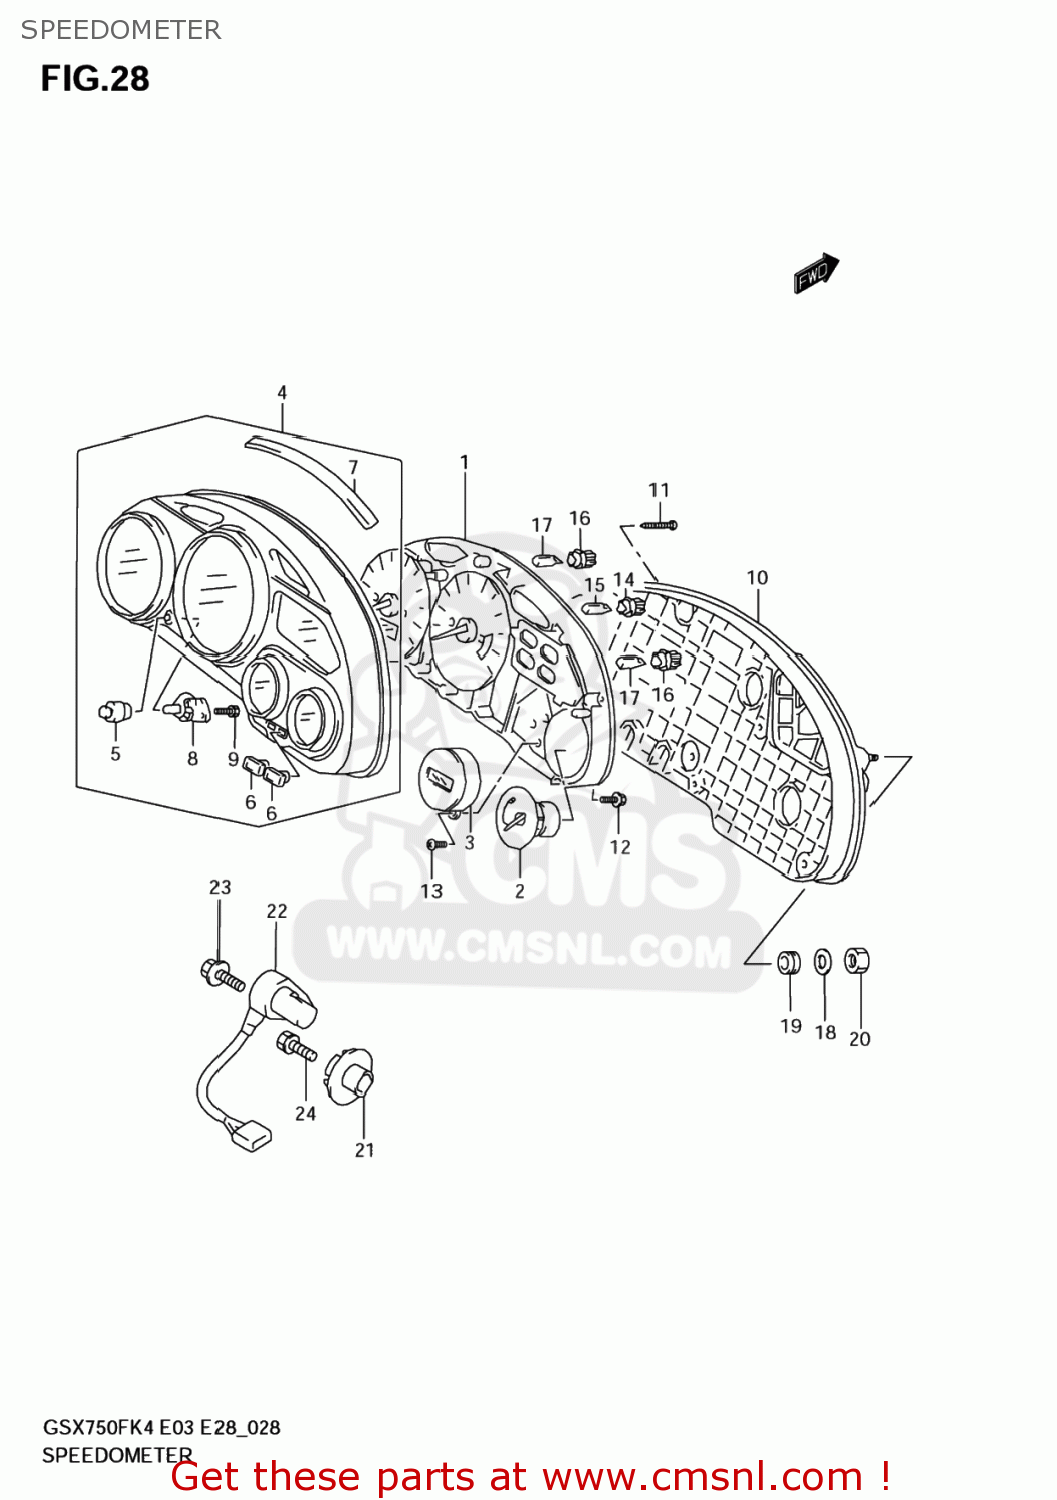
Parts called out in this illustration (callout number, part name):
1	SPEEDOMETER
2	FUEL,METER
3	CLOCK ASSY
4	VISOR ASSY
5	SWITCH,GUM
6	SWITCH,GUM
7	PACKING (NAS)
8	ATTACHMENT,SWITCH
9	SCREW(3X10)
10	CASE ASSY
11	SCREW
12	SCREW
13	SCREW
14	SOCKET(T:6.5)
15	BULB(12V1.7W,T6.5)
16	SOCKET
17	BULB(14V1.4W,T5)
18	WASHER(6.5X22X1.6)
19	CUSHION
20	NUT 6MM
21	ROTOR,SPEED
22	SENSOR,SPEED
23	BOLT
24	BOLT
